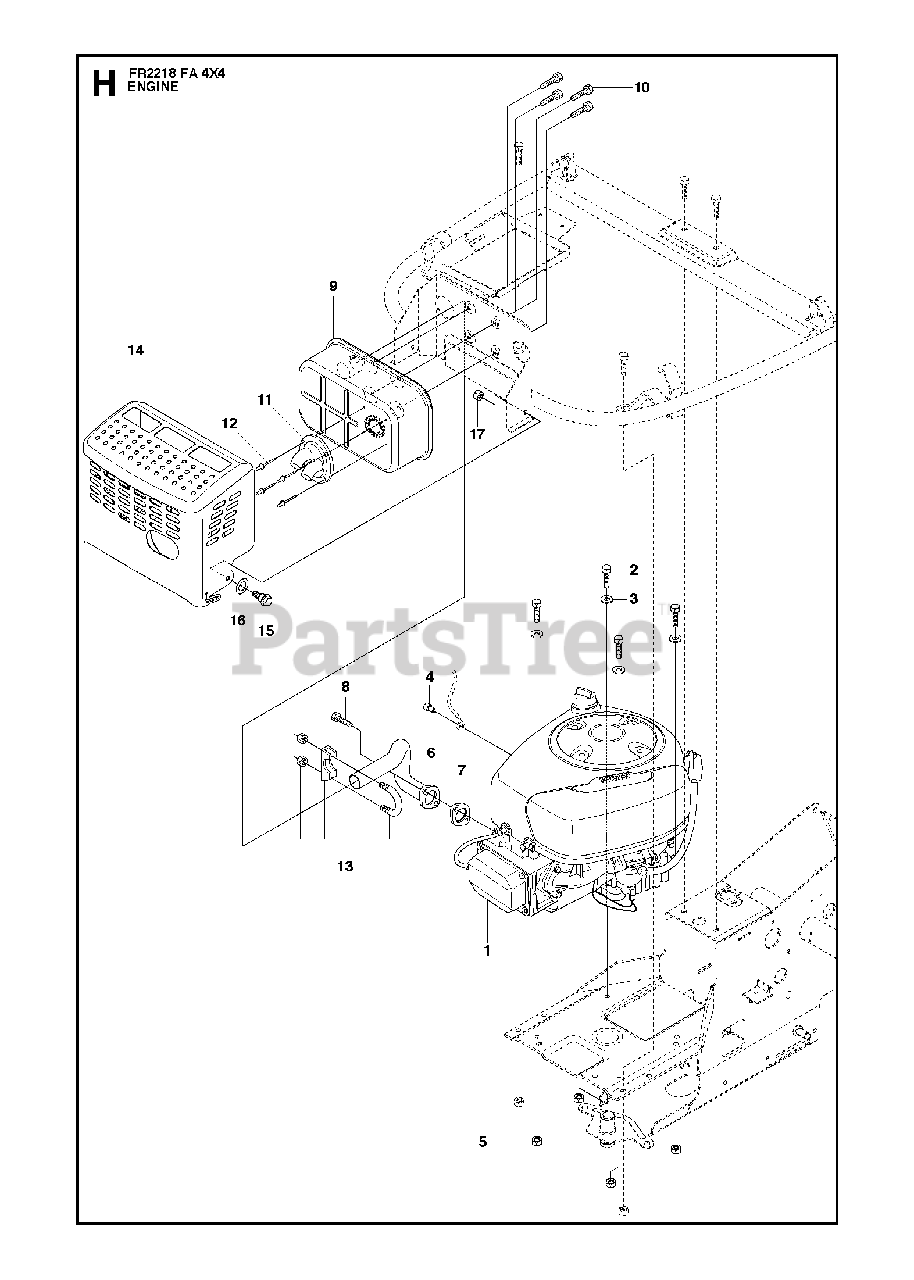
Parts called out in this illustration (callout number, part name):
3	WASHER BRB 8.4X17
5	LOCKNUT M8
9	MUFFLER
16	SPRINGWASHER
17	LOCKNUT M8
